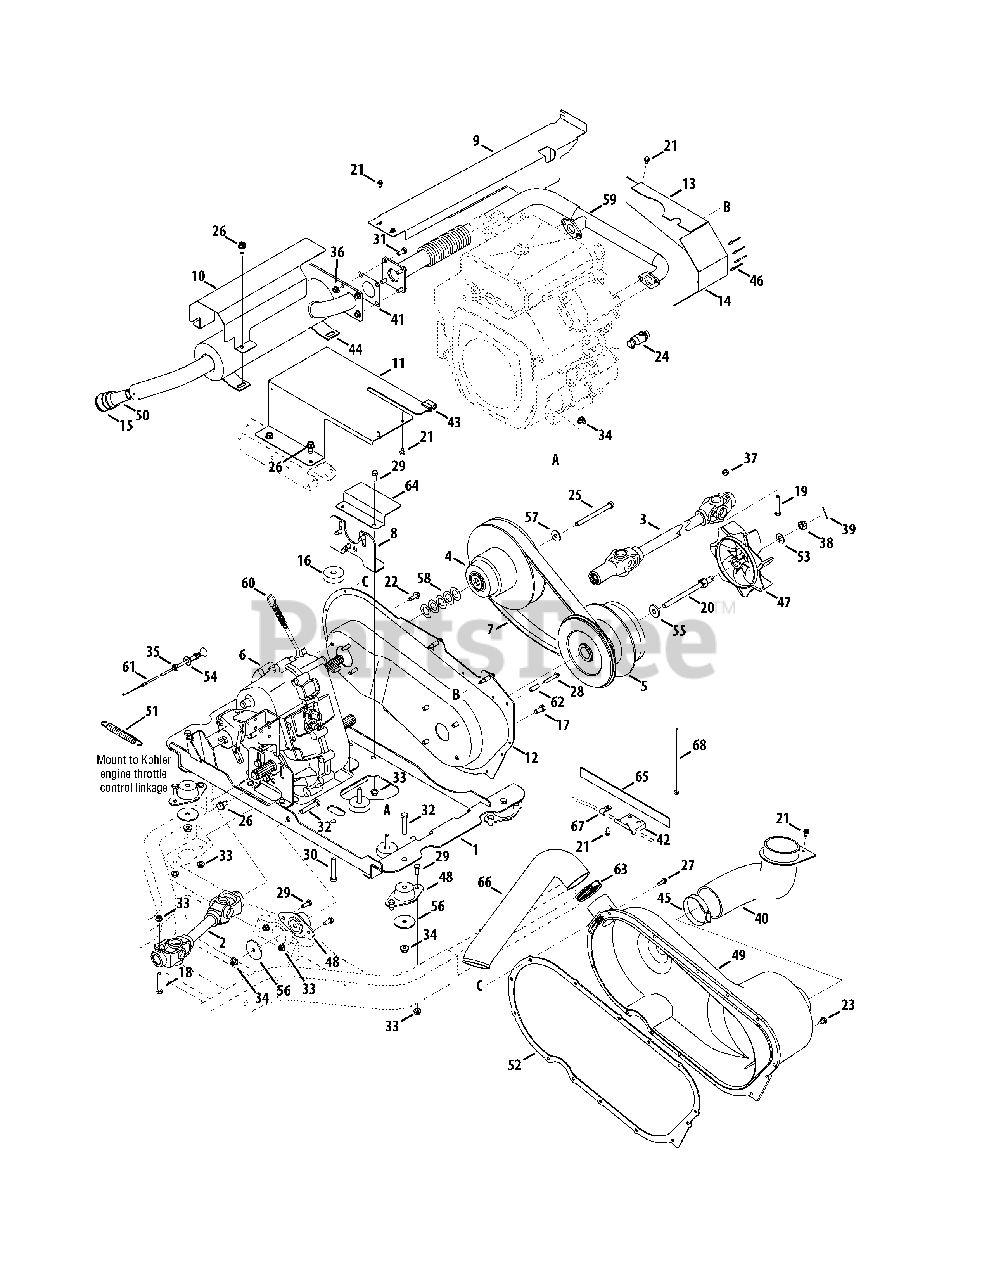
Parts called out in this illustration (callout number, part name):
1	Tray Assembly, Engine, Kohler
2	Shaft Assembly, Rr/prop
3	Shaft Assembly, Frt/prop, Hilliard
4	Clutch Assembly, Cvt, Driven
5	Clutch Assembly, Cvt, Driver, Cvr
6	Case Assembly, Transfer
7	Belt, Cvt, 4x4
9	Cover, Heat, Shield
10	Exhaust, Shield, Heat
13	Cover, Engine, Kohler
14	Cover, Engine, Rr, Kohler
16	Spacer, Engine, Kohl
17	Hex Head Screw, 3/8-16, .75
18	Hex Head Screw, 5/16-18, 2.00
19	Hex Head Screw, 5/16-18, 1.875
20	Hex Head Screw, 7/16-20, 5.00
21	Screw, Tt, 1/4-20, 0.500
22	Screw, Tt, 5/16-18, .875
23	Screw, B, 5/16-12, 0.500
25	Hex Head Screw, 3/8-24, 3.50
26	Screw, Tt, 3/8-16, 0.750
27	Screw, Tt, 1/4-20, 0.750
28	Screw, Tt, 1/4-20, 1.625
29	Hex Head Screw, 5/16-18, .75
30	Hex Head Screw, 3/8-16, 2.25
31	Hex Head Screw, 5/16-18, .875
32	Hex Head Screw, 3/8-16, 2.00
33	Nut, Flange Lock, 5/16-18, Nylon
34	Nut, Flange Lock, 3/8-16, Nylon
35	Nut, Jam, 3/8-24
36	Nut, Flange Lock, 5/16-18
37	Nut, Hex Lock, 5/16-18, Ctrlk
38	Nut, Hex, 1/2-20, Gr5, Slot
39	Pin, Cot, 3/32, 1.0
40	Tube, Cvt, Intake
41	Gasket, Engine
42	Bracket, Cable Shield
43	Heat Baffle Seal
45	Clamp, Hose, Adj.
46	Rivet, Pop, .125 Od, #42
47	Impeller, Blo
48	Compression Mount, Eng, Head
49	Cover, Cvt
50	Spark Arrester Screen
51	Spring Latch
52	Seal, CVT, Cover
53	Washer, Flat, .510 x 1.00 x .060
54	Washer, Flat, .406 x .875 x .059
55	Washer, Flat, .450 x 1.250 x .164
56	Washer, Flat, .38 x 2.00 x .12
57	Washer, Bell, .396 x 1.140 x .095
58	Washer, Flat, .793 x 1.368 x .025
59	Pipe, Exhaust, Kohl
60	Cable, Throttle Control, Kohler
61	Cable, Choke Control, Kohl
62	Spacer, .260 Id x .375od x 1.0l
63	Clamp, Hose
64	Shield, Harness
65	Heat Shield Sleeve
66	Hose, CVT, Exhaust
67	Clamp, Hose
68	Tie, Cable
